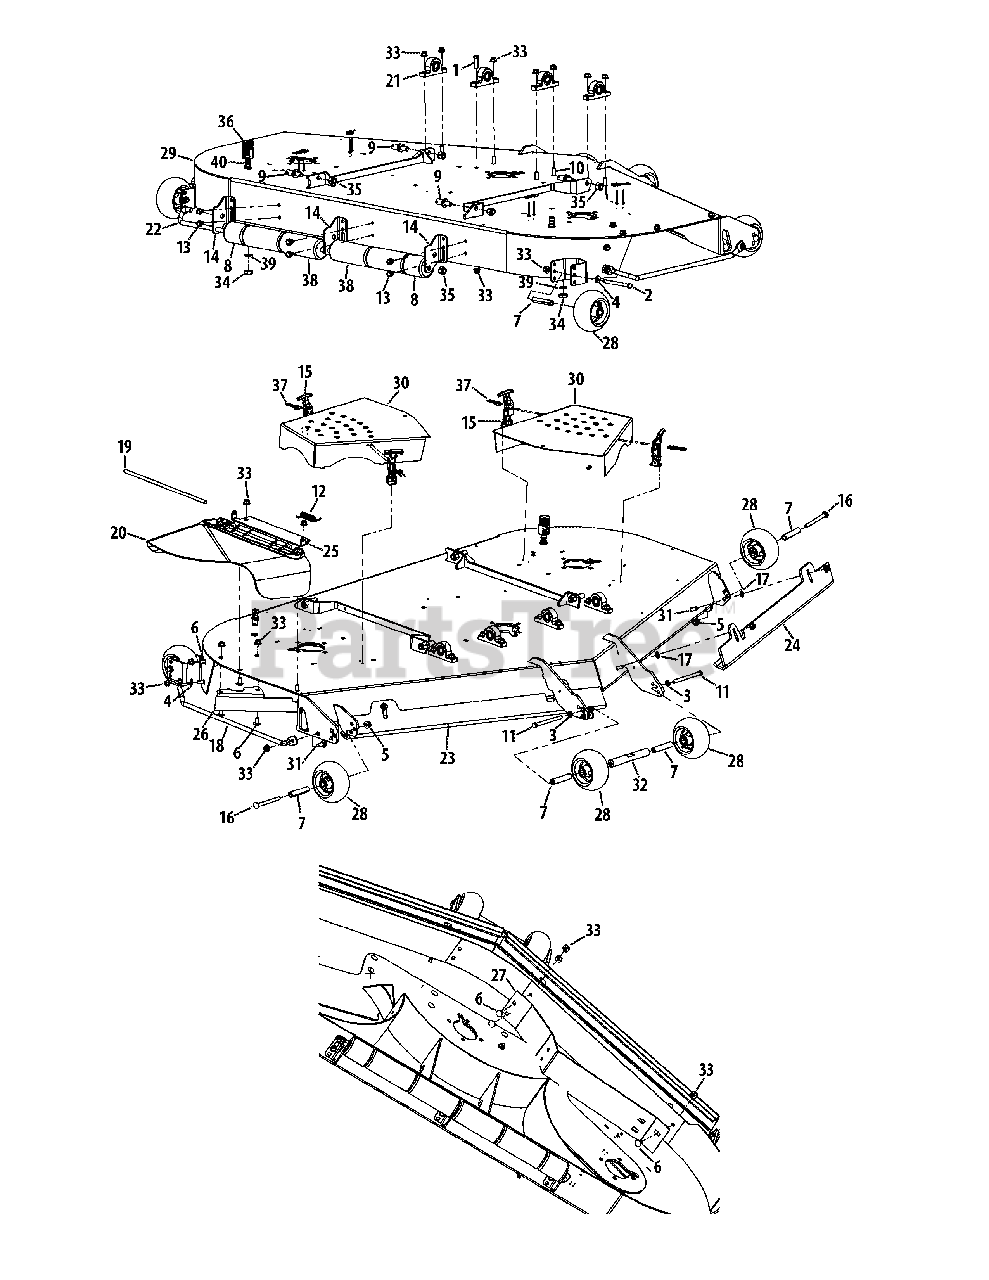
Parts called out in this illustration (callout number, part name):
1	Hex Cap Screw, 3/8-16, 1.25
2	Hex Cap Screw, 3/8-16, 4.00
3	Lock Washer, .375 x .680 x .100
4	Flat Washer, 3/8
5	Flange Lock Hex Nut, 3/8-16
6	Carriage Bolt, 3/8-16 x .75
7	Wheel Spacer, .390 x .620 x 3.04
8	Grass Catcher Roller
9	Pin, 5/8 Dia. x 1.2
10	Carriage Screw, 3/8-16 x 1.25
11	Hex Cap Screw, 3/8-16 x 4.50
12	Torsion Spring, 0.4 x 2.16
13	Hex Washer Screw, 3/8-16, .5
14	Deck Roller Mount Bracket
15	T-Handle Latch Draw
16	Carriage Bolt, 3/8-16 x 4.00
17	Push Retainer
18	Finger Guard
19	Pin, .375 x 14.06
20	Chute Deflector
21	Pillow Block, Steel
22	J-Hook w/ Threaded Roller
23	Right Hand Front Adjustment Skirt
24	Left Hand Front Adjustment Skirt
25	Chute Deflector Bracket
27	Baffle, 72" Adjustment
28	Complete Wheel, 5.00 Dia.
29	72" Deck Assembly
30	Deck Belt Cover
31	Carriage Bolt, 3/8-16 x 1
32	Ball Wheel Mounting Shaft
33	Flange Lock Hex Nut, 3/8-16
34	Hex Nut, M16-1.5
35	Lock Nut, Nylon Insert, 1/2-13
36	Water Nozzle Adaptor
37	Pop Rivet, 3/16
38	Front Roller
39	Lock Washer, 17 x 23.8 x 1.95
40	Deck Water Nozzle
